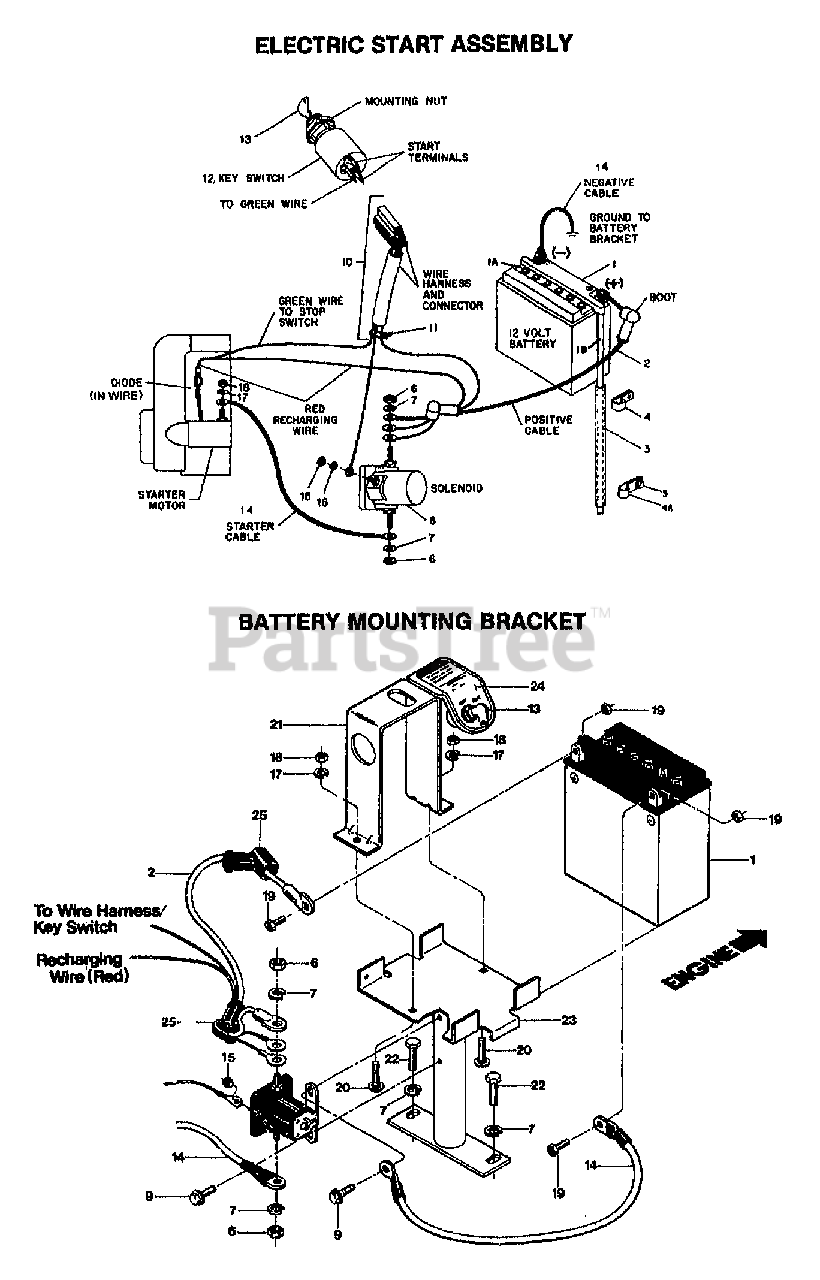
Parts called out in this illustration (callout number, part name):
1	BATTERY
1A	CAP-YELLOW
1A	CAP-BATTERY WHITE (PONY)
2	CABLE-BATTERY
3	TUBING-RUBBER (PLASTIC)
4	CLAMP (SMALL)
4A	CLAMP-VENT TUBE 9/16 OPC (LARGE)
5	SCR-HHC 5/16-18X.75 GR 5 ZP
6	NUT-HEX 5/16-24
7	WASHER-LK .312 ZP
8	KIT-SOL W/HDW (INCL. NUTS & WASHERS FOR CABLES & WIRES)
9	SCR-HWH 1/4-20 X .5 STH
10	HARNESS-WIRE 3.5
11	TIE-TWIST LOCK
12	KEYSWITCH W/KEYS
13	KEYS(1 PAIR) FOR SWITCH
14	CABLE-BATTERY 13.5"
15	NUT-HH M10-32X.125
16	WASHER-EXTERNAL TOOTH 1
17	WASHER-LK .25 ZP
18	NUT-HEX 1/4-20 ZP
19	HDW PKG-BATTERY TERMINAL
20	SCR-CARR 1/4-20X1.25
21	PLATE-KEYSWITCH W/DECAL (INCL. #20820 DECAL)
22	SCR-HH 5/16-18X1.0 G5 ZP
23	BRKT-BATTERY OPC PNT
24	DECAL-KEYSWITCH
